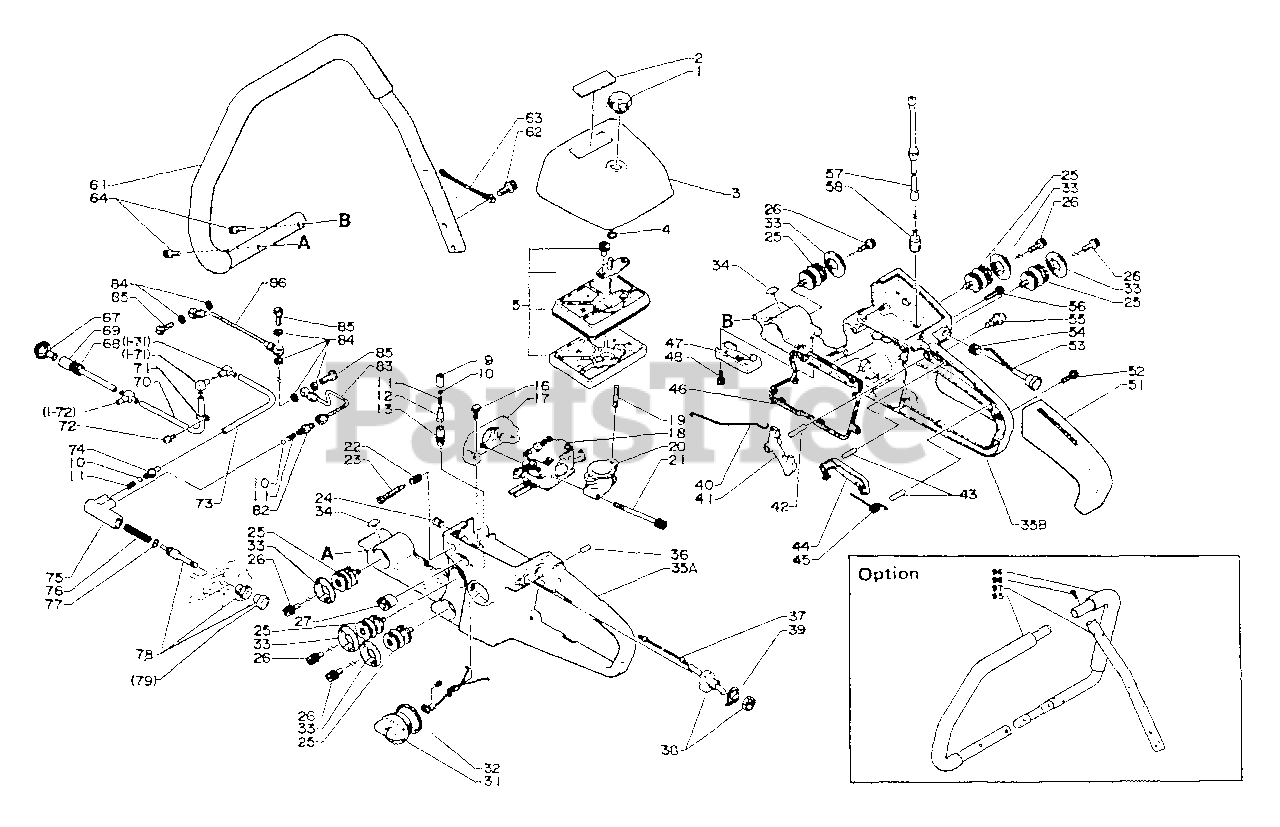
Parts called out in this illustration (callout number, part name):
2	PLATE, MODEL
3	COVER, AIR FILTER
4	RING, RETAINING - 11
5	AIR CLEANER ASSY
9	BREATHER
10	VALVE, BALL
11	SPRING, VALVE
12	BREATHER
13	CONNECTOR
16	SCREW - 5X20
17	CASE, CARBURETOR
18	CARBURETOR
19	STUD
20	PIPE - INTAKE
21	SCREW - 5X75
22	SPRING
23	SCREW, IDLE ADJUST
24	GROMMET
25	CUSHION
26	SCREW - 5X15
27	GROMMET
31	CAP ASSY
32	O-RING - 29
33	CAP, CUSHION
34	STOPPER
35	HANDLE ASSY - REAR
35A	HANDLE ASSY - REAR
35B	HANDLE ASSY - REAR
36	PIN - LOCATING
37	LEAD - GROUND
38	IGNITION SWITCH ASSY
39	LABEL - STOP
40	ROD, THROTTLE
41	TRIGGER, THROTTLE
42	PIN - SPRING -- 5X25
43	PIN - SPRING
44	LOCKOUT, THROTTLE
45	SPRING, LOCKOUT LEVER
46	GASKET, FUEL TANK
47	COVER, PUMP
48	SCREW - 4X12
51	GRIP, HANDLE - REAR
52	SCREW - 4X16
53	ROD, CHOKE
55	LATCH, THROTTLE
56	SCREW - 4X20
57	PIPE - FUEL
58	FILTER, FUEL
61	HANDLE - FRONT
62	SCREW - 6X25
63	LEAD - GROUND
64	SCREW - 5X20
67	FILTER, OIL
68	GROMMET
69	PIPE, FUEL - CORRUGATED
70	PIPE - 3X6X130
71	CLIP
72	SCREW - 4X10
73	PIPE - OIL
74	CONNECTOR
75	BODY, OIL PUMP
76	SPRING, OIL PUMP
77	O-RING - 6
78	PISTON, OIL PUMP
79	PUSH BUTTON
82	CONNECTOR
83	PIPE - OIL
85	BOLT
86	PIPE - OIL
95	HANDLE - LEFT
96	HANDLE - RIGHT
97	SUPPORT
98	SCREW - 5X20
